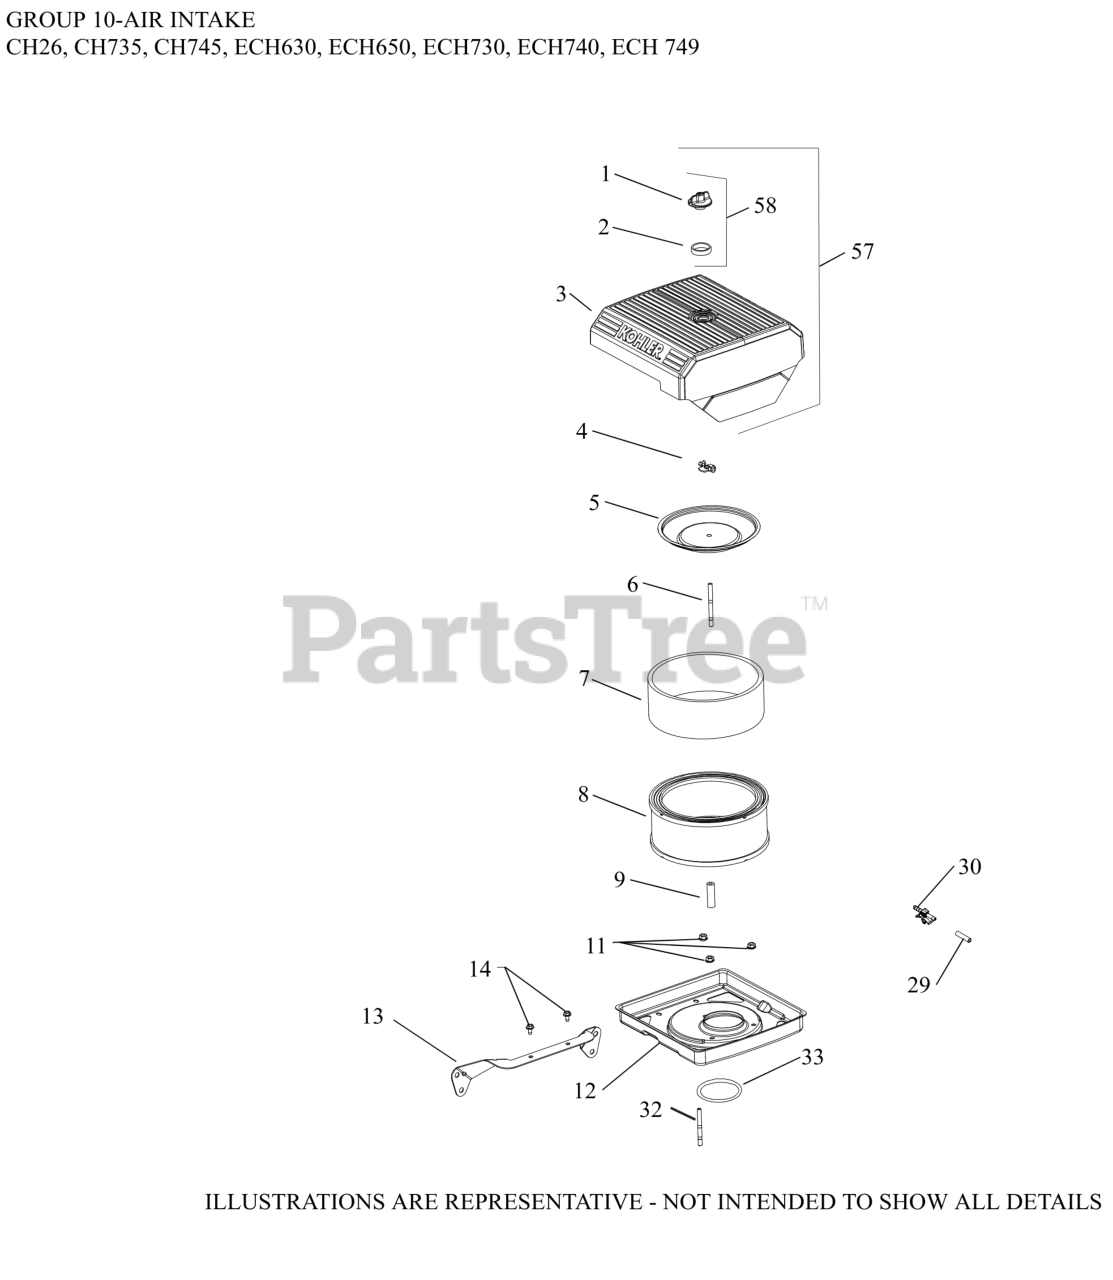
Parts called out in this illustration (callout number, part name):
1	KNOB, COVER
3	COVER, AIR CLEANER
4	NUT, WING
5	COVER, INNER AIR CLEANER
6	STUD, LOW PROFILE A/C
7	PRE-CLEANER (HIGH)
8	AIR FILTER ELEMENT
11	NUT, FLG M6X1.0
12	BASE, AIR CLEANER
13	AIR CLEANER BRACKET
14	SCREW, THREAD FORMING
29	CAP, MASKING
30	CONNECTOR, EVAPORATIVE
33	O-RING, AIR CLEANER BASE
57	KIT, AIR CLEANER COVER
58	KIT, KNOB W/SEAL
